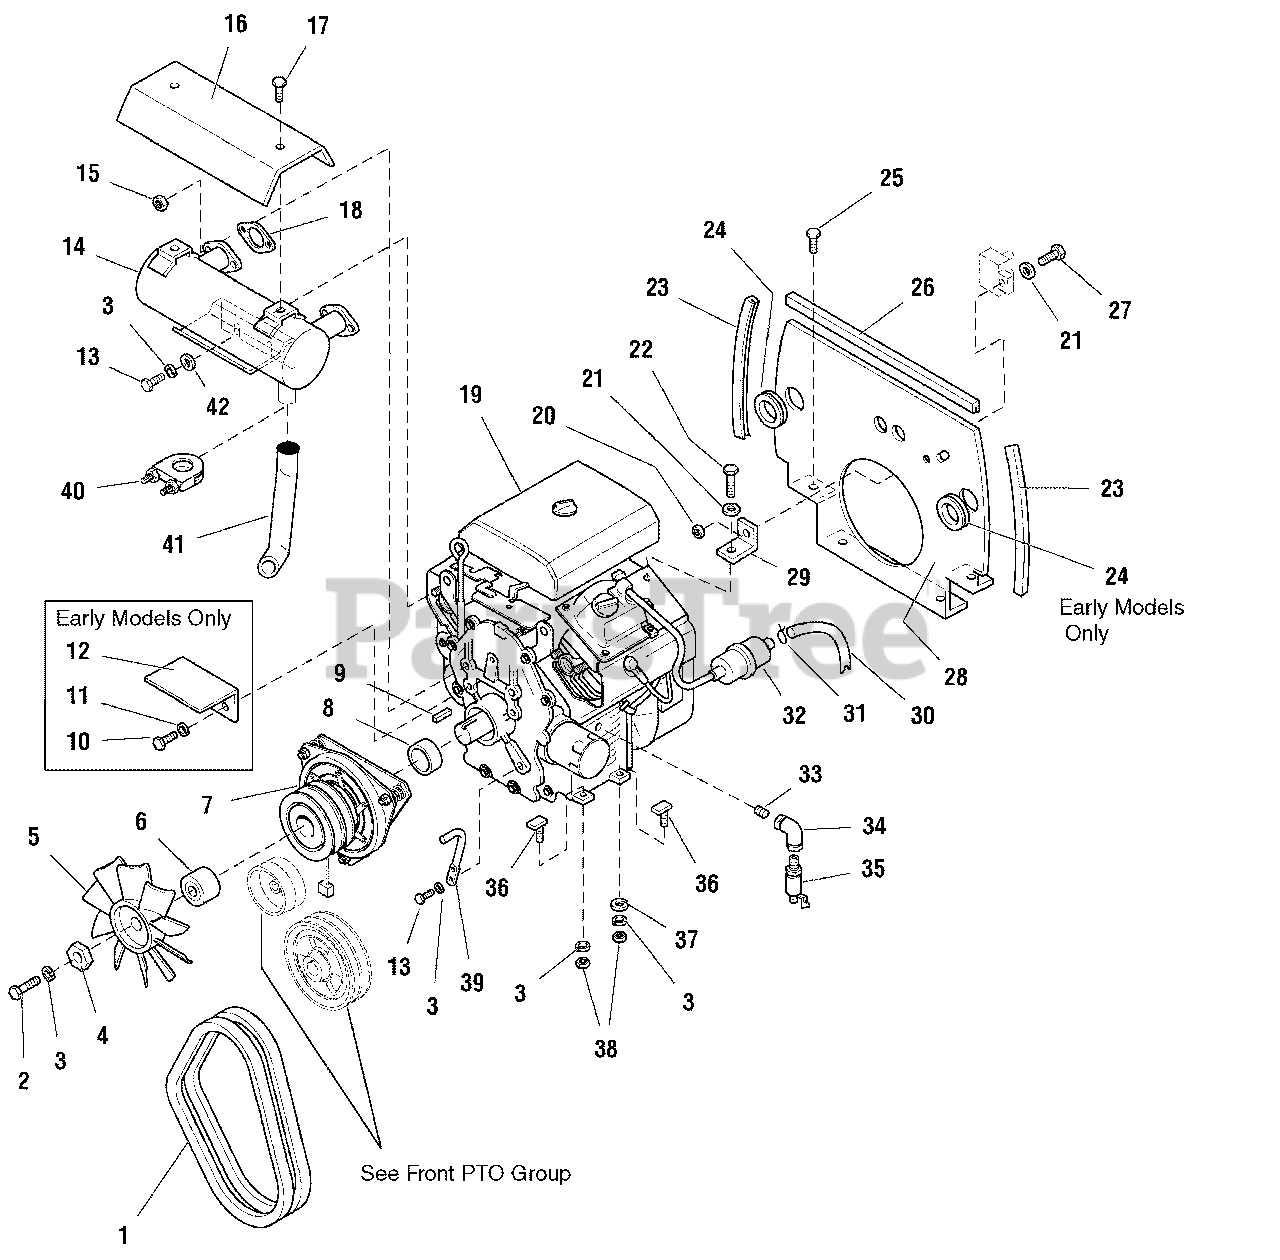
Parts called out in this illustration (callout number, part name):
1	BELT, P.T.O. (Matched Set of 2 Belts)
2	CAPSCREW, Hex Head, 7/16-2 x 3.25
3	LOCKWASHER, 7/16
4	WASHER, Hex, 7/16
5	FAN, Electric Clutch
6	SPACER, Clutch Fan
7	ELECTRIC CLUTCH
8	SPACER, Clutch
10	CAPSCREW, Hex Head, 3/8-16 x 5/8
11	LOCKWASHER, 3/8
12	SHIELD, Heat (Early models only)
13	CAPSCREW, Hex Head, 7/16-14 x 1
15	NUT, Hex
16	HEAT SHIELD
17	CAPSCREW, Hex Head, Taptite, 5/16-18 x 1/2
18	GASKET, Exhaust Manifold
19	ENGINE, 23HP Kohler
19	ENGINE, 20HP Kohler
19	ENGINE, 25HP Kohler
20	NUT, Hex Nylon 1/4-20
21	WASHER, 1/4
22	CAPSCREW, Hex Head (Engine Bolt)
23	EDGING, Side 12.5 Lg
24	GROMMET (Early models only)
25	CAPSCREW, Hex Head, Taptite, 5/16-18 x 3/4
26	EDGING, Top 18 Lg
27	CAPSCREW, Hex Head, 1/4-20 x 3/4
28	SHIELD, Firewall
29	ANGLE BRACKET
30	HOSE, Fuel 60-1/2 Lg
31	CLAMP, Hose
32	FUEL FILTER
33	NIPPLE, Pipe 3/8 x 1-1/4
35	VALVE, Shut Off
36	L-BOLT, 3/8-16 x 1.75
37	WASHER, 3/8
38	NUT, Hex Full 3/8-16
39	ROD, Anti Rotation
41	ELBOW, Exhaust
42	WASHER, 5/16
